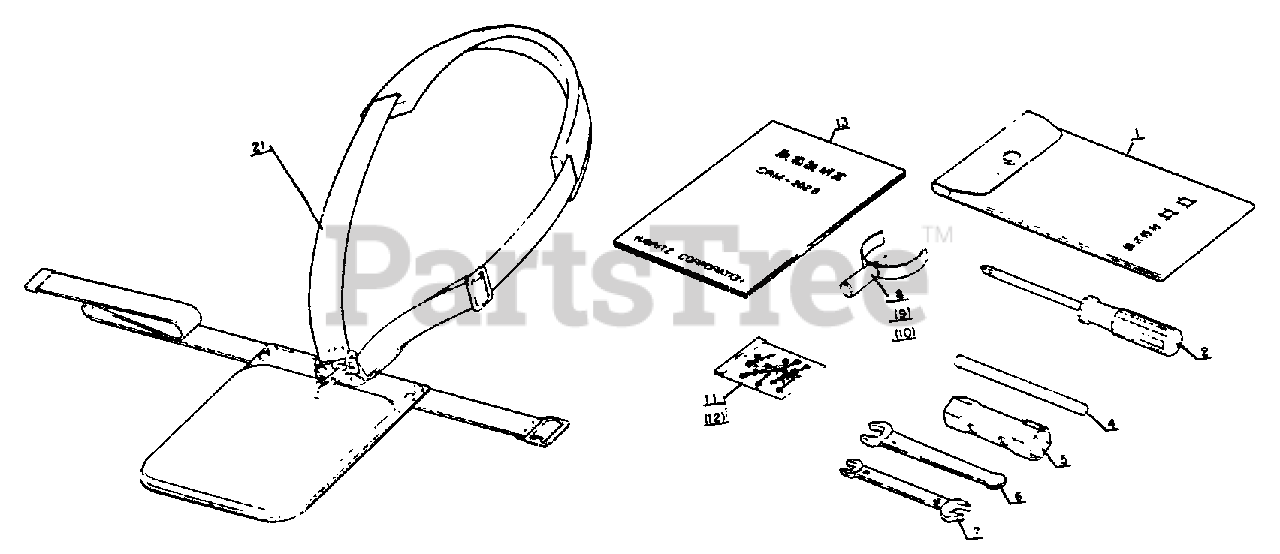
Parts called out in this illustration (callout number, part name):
1	BAG, TOOL
2	SCREWDRIVER - CROSS HEAD
4	ROD, HANDLE
5	BOX WRENCH - 17×19
6	SPANNER 13
7	SPANNER 8×10
8	FITTING TOOL
11	PIN - 2×22
13	OWNER'S MANUAL
14	SERVICE TOOL KIT
21	HARNESS ASSY
